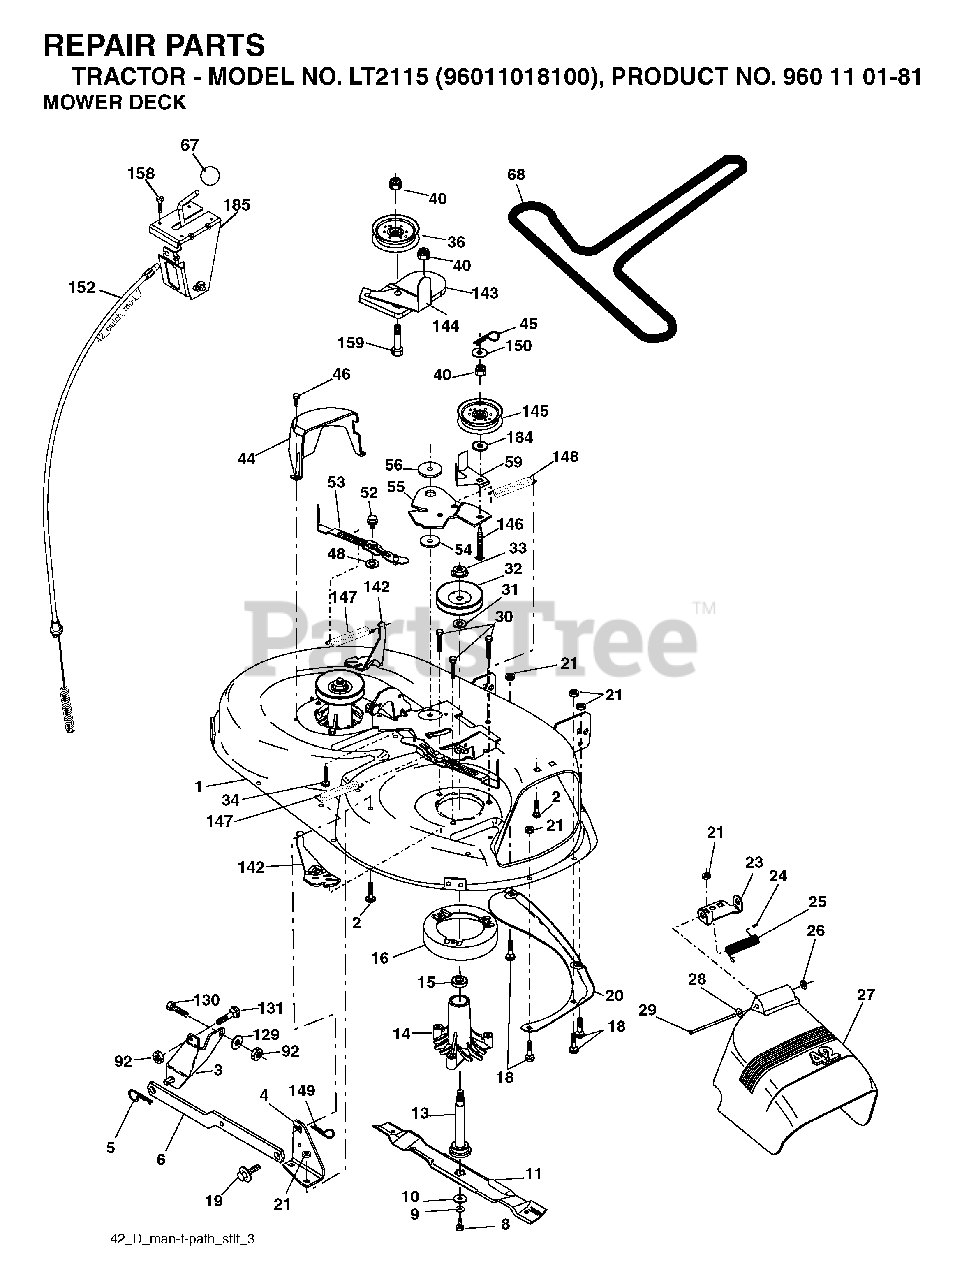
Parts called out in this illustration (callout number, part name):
1	42" DECK KIT
2	BOLT
3	BRKT ASM SWAY BAR
4	BRACKET SWAY BAR 42" DECK
5	RETAINER-SPRNG RB
6	BAR SWAY DECK
8	BLADE BOLT
9	LOCKWASHER
10	WASHER.BLADE
11	42" HI-LIFT BLADE
13	SHAFT ASM VENT
14	HSG MANDREL
16	STRIPPER, MWR ROUND
18	BOLT
19	BOLT SHD 5/16-18
20	BAFFLE.VORTEX
21	LOCKNUT
23	BRKT, DEFL. MOWER
24	CAP-SLEEVE LT
25	SPRING TORSION
26	NUT PUSH M
27	SHIELD DEFLECTOR
28	WASHER
29	ROD.HINGE
30	SCREW, WASHER HEAD
31	WASHER.SPACER.MANDREL
32	PULLEY/MANDREL
33	NUT.FLANGE.LOCK.TOP
34	BOLT.3/8-16X1.50
36	FLAT IDLER PULLEY
40	NUT LOCK FLG 3/8-16 UNC
44	GUARD MANDREL LH BLACK
45	RETAINER M
46	SCREW.1/4-20X5/8
53	ARM BRAKE ASSY
55	ARM IDLER 42" MOWER LT/YT
56	SPACER.RETAINER.MOWER
59	GUARD, BELT
67	KNOB T (3/8 HOLE)
92	NUT
111	BRACKET, WHEEL
112	BRACKET, WHEEL
113	BOLT.5/16HEX.WHS.HD
117	WHEEL.GAGE.HALF.SPOKED
118	LOCKNUT
119	WASHER
129	WASHER
131	BOLT D
142	ARM SPRING BRAKE MOWER
143	BRACKET, ARM IDLER
144	KEEPER.BELT.42".CLUTCH.CABLE
145	PULLEY
146	BOLT, CARRIAGE IDLER BLACK
148	IDLER RETURN SPRING
149	SPRING.RETAINER.YELLOW.ZINC
150	WASHER LT
152	42" CLUTCH CABLE
158	SCREW
159	BOLT
184	WASHER
185	HEAD ASM. CABLE CLUTCH
